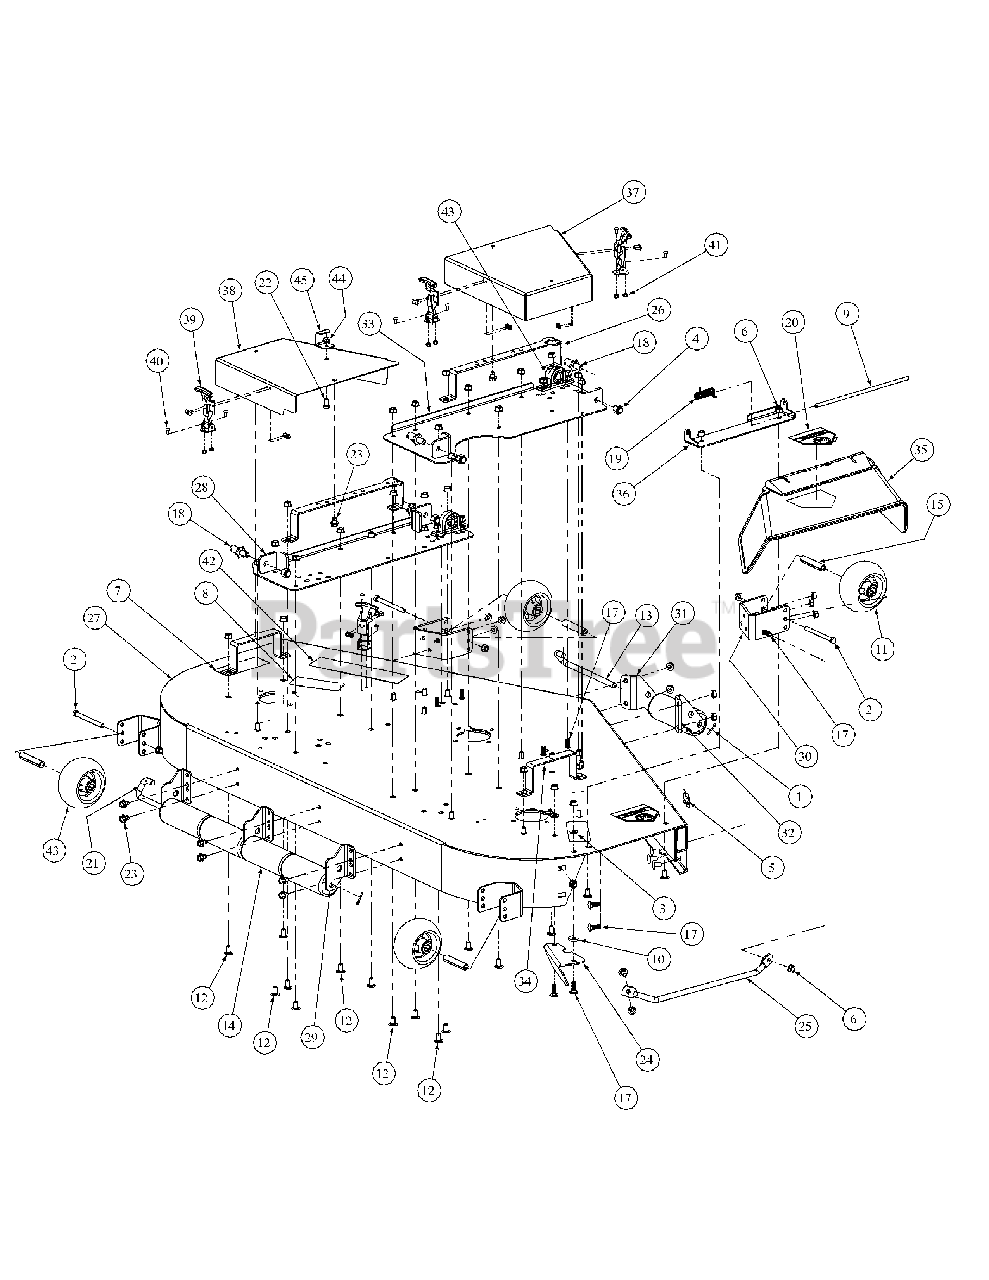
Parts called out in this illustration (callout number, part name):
1	Cotter Pin, .125 Dia. x 1.0
2	Hex Cap Screw, 3/8-16, 3.75
3	Flat Washer, 3/8
4	Lock Nut, Nylon Insert, 1/2-13
5	Label, 60"
6	Flange Lock Hex Nut, 3/8-16
7	Decal, Rotating Blade
8	Decal, Warning Shield Missing
9	Chute Deflector Rod
10	Idler Washer
11	Complete Wheel, 5.00 Dia.
12	Carriage Bolt, 3/8-16 x .75 Lg.
13	Roller Pin, 1/2 Dia. x 7.31 Lg.
14	Front Roller
15	Wheel Spacer
17	Carriage Bolt, 3/8-16 x 1
18	Pin, 5/8 Dia. x 1.2 Lg.
19	Torsion Spring, 0.4ID x 2.16Lg
20	Decal, Danger Hand and Feet
21	Roller Pin
22	Hex Cap Screw, 5/16-18 x .75
23	Hex Index Washer Screw, 3/8-16, .5
24	Chute Bracket
25	Finger Guard
26	Belt Cover Support
27	60" Deck Assembly
28	Left Hand Mount Deck Bracket Assembly
29	Deck Roller Mount Bracket
30	Anti-Scalp Wheel Front Mount Bracket
33	Right Hand Deck Bracket Assembly
34	Outer Belt Cover Support Assembly
35	Chute Deflector
36	Chute Deflector Bracket
37	Right Hand Deck Belt Cover Weldment
38	Left Hand Deck Belt Cover Weldment
39	T-Handle Latch Draw
40	Phillips Head Screw, 10-32
41	Lock Nut, Nylon Insert, 10-32
42	Commercial Mower Label
43	Pillow Block
44	Nut, 5/16-18, Hex Flange Lock
45	Stop Bracket
